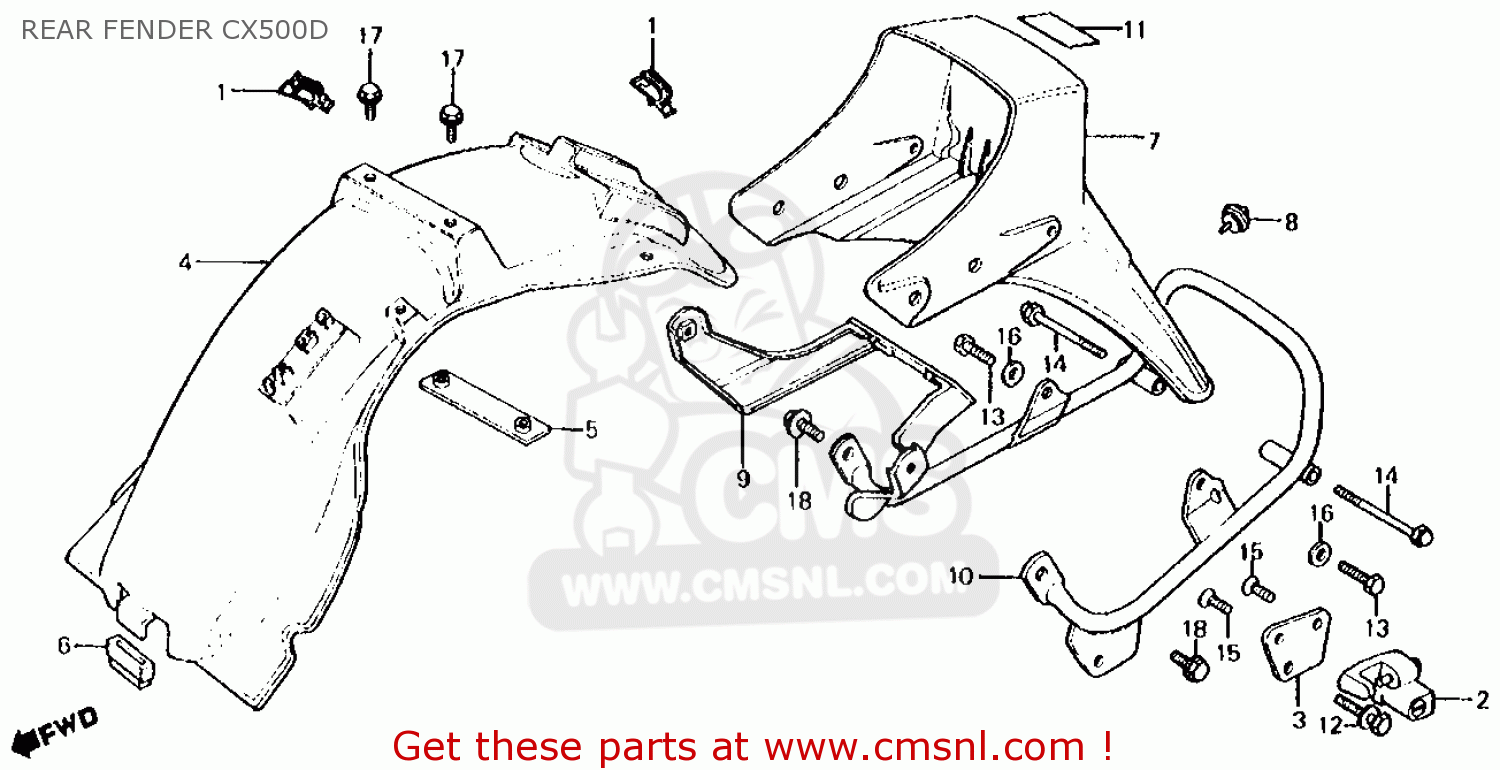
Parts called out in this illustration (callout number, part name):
1	CLIP, WIRE HARNES
2	HOLDER,HELMET
3	PLATE,HELMET HOL.
4	FENDER,REAR
5	PLATE,RR.FENDER
6	RUBB,FENDERCUSHON
7	COWL,RR.*R-8C-S*
8	PLUG,RR.COWL
9	STAY,RR.COWL
10	BUMPER,RR.
11	MARK,TIRE CAUTION
12	BOLT, SPEC. 8X16
13	BOLT,HEX.8X20
14	BOLT HEX CAP 6X70
15	SCREW,FLAT,6X10
16	WASHER 8MM
17	BOLT,FLANGE,6X16
18	BOLT,FLANGE,8X16
